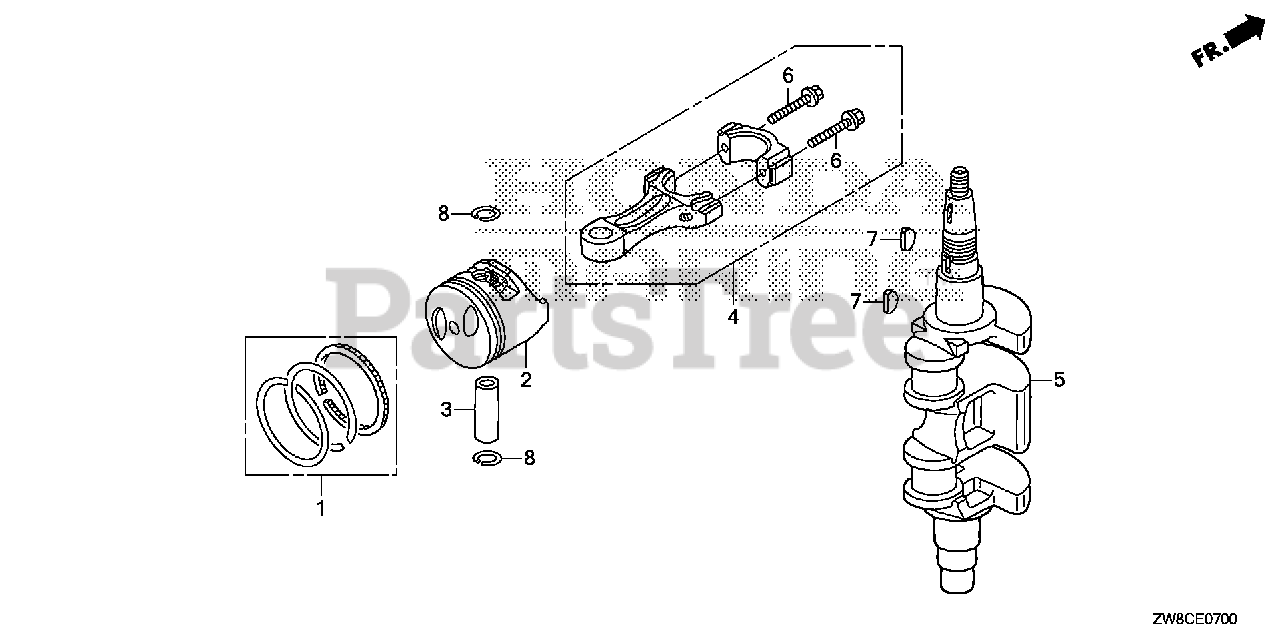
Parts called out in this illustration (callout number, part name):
1	RING SET, PISTON (STD)
3	PIN, PISTON
4	ROD, CONNECTING
5	CRANKSHAFT
6	BOLT, CONNECTING ROD (6X34)
7	KEY, SPECIAL (16X13)
8	CLIP, PISTON PIN (16MM)
